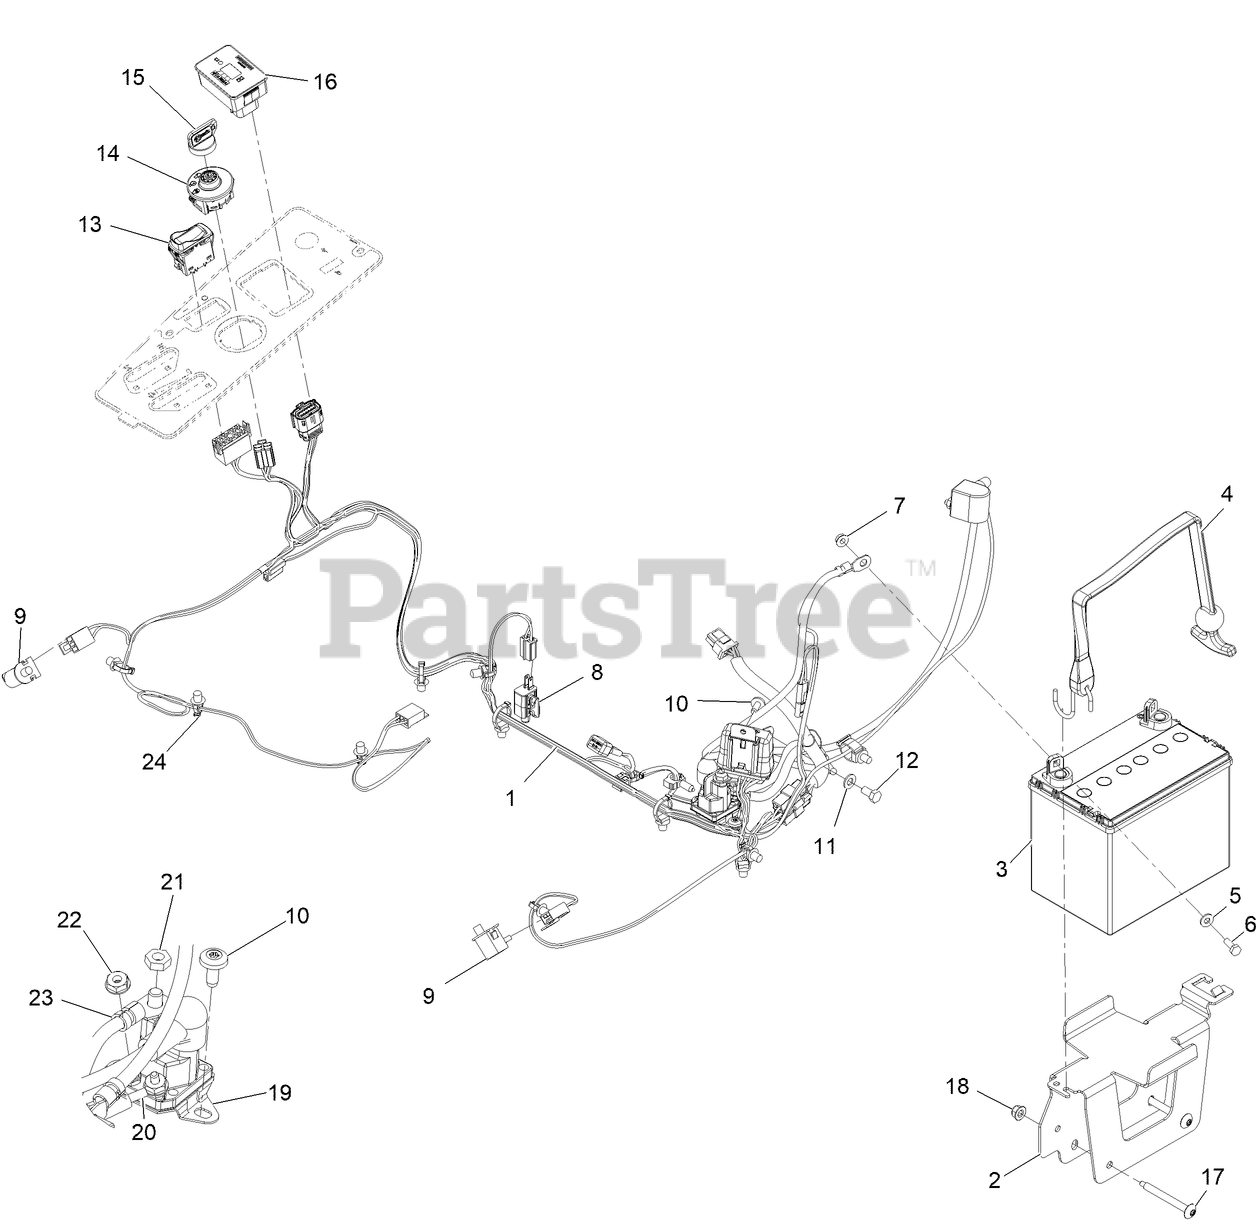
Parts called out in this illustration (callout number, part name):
1	Harness-Main
2	TRAY-BATTERY
3	Battery
4	STRAP, BUNGEE
5	WASHER-FLAT
6	SCREW-HH
9	SWITCH-BAIL
10	SCREW-TORX
11	WASHER-PLAIN
12	SCREW-HH
13	SWITCH-ROCKER, ON-NONE-ON
14	SWITCH-IGNITION
15	KEYS-IGNITION (SPARE PAIR
15	KEY-IGNITION
16	MODULE ASM
17	SCREW-TORX
18	NUT-HF, NI
19	SOLENOID
20	ADAPTER-HARNESS, WIRE
21	NUT-JAM
22	NUT-KEPS
23	CABLE-BATTERY, POSITIVE
24	CLIP-HARNESS
